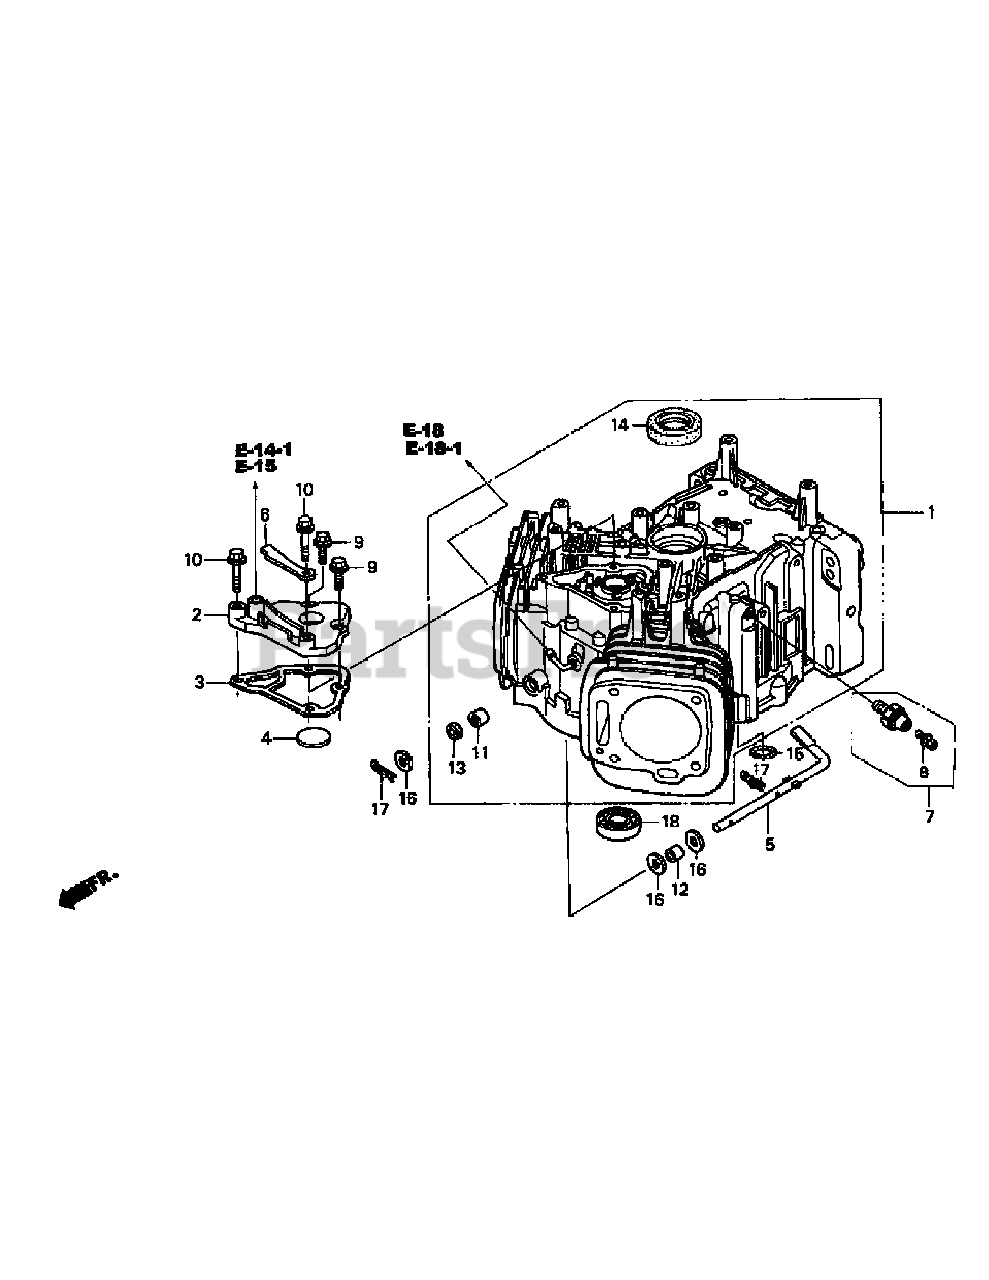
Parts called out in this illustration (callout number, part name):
1	Cylinder Assy.
2	Breather Cover
3	Breather Cover Gasket
4	Breather Valve
5	Governor Arm Shaft
6	Wire Clamp
7	Oil Pressure Switch
8	Screw Washer (4x8)
9	Flange Bolt (6x16)
10	Flange Bolt (6x32)
11	Needle Bearing (8x12.7x11.1)
12	Needle Bearing (8x12x10)
13	Oil Seal (8x14x5)
14	Oil Seal (38x58x9)
15	O-Ring (13x3.0)
16	Plain Washer (8mm)
17	Lock Pin (8mm)
18	Radial Ball Bearing
